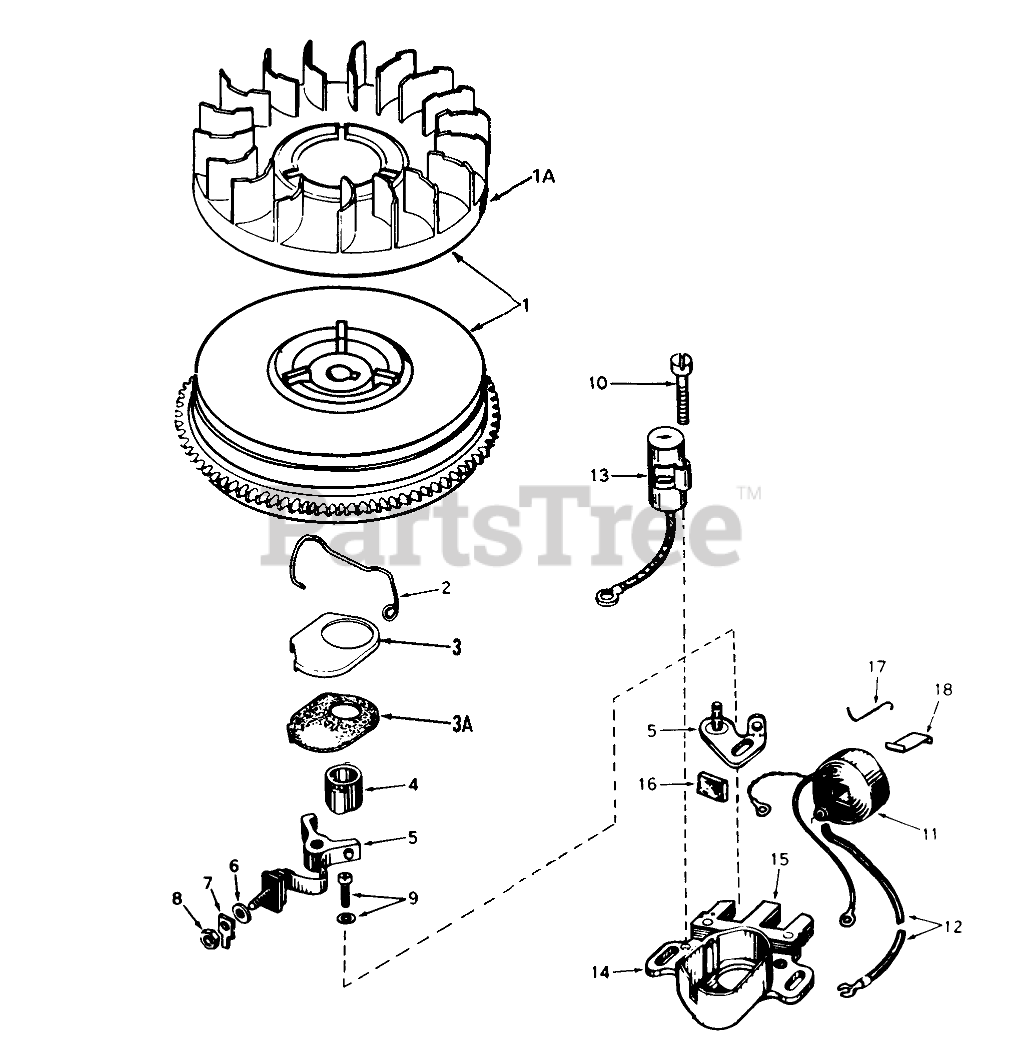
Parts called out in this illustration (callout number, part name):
1	Flywheel (Incl. Nos. 1A, 3 & 3A)
2	Spring Breaker Box
3	Cover-Dust
3A	Gasket, Dust Cover
4	Cam-Breaker
5	Breaker Assy.
7	Terminal, Ground
9	Breaker Screw
10	Condenser Screw
11	Coil Assy. (Incl. No. 12)
12	Wire, Lead
13	Condenser
14	Core & Plate
15	Stator Assy. (Incl. Nos. 2, 3, 3A ,5 thru 14 & 16 thru 18)
16	Felt,Cam Wiper
17	Clip, Coil
18	Spring Coil Wedge
